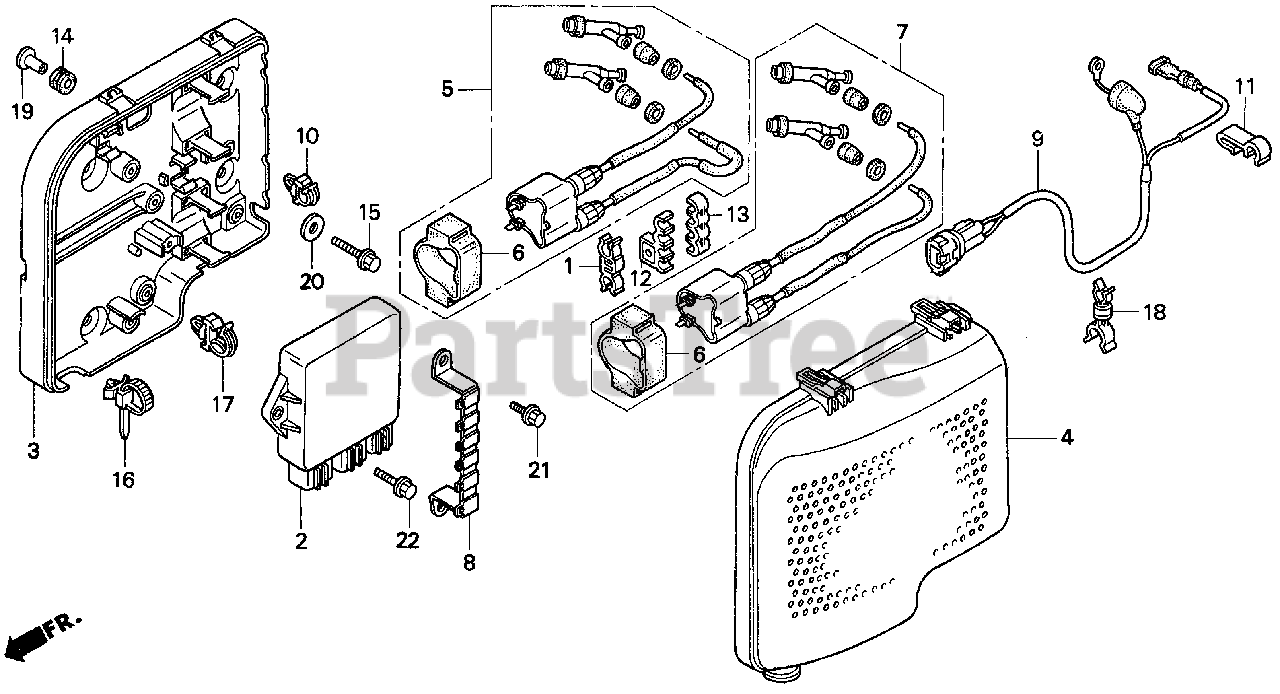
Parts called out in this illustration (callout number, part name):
4	COVER, IGNITION CONTROL MODULE
15	BOLT, FLANGE (6X25)
16	STRAP, CABLE (118MM) *NH1L* (BLACK)
20	WASHER, PLAIN (6MM)
